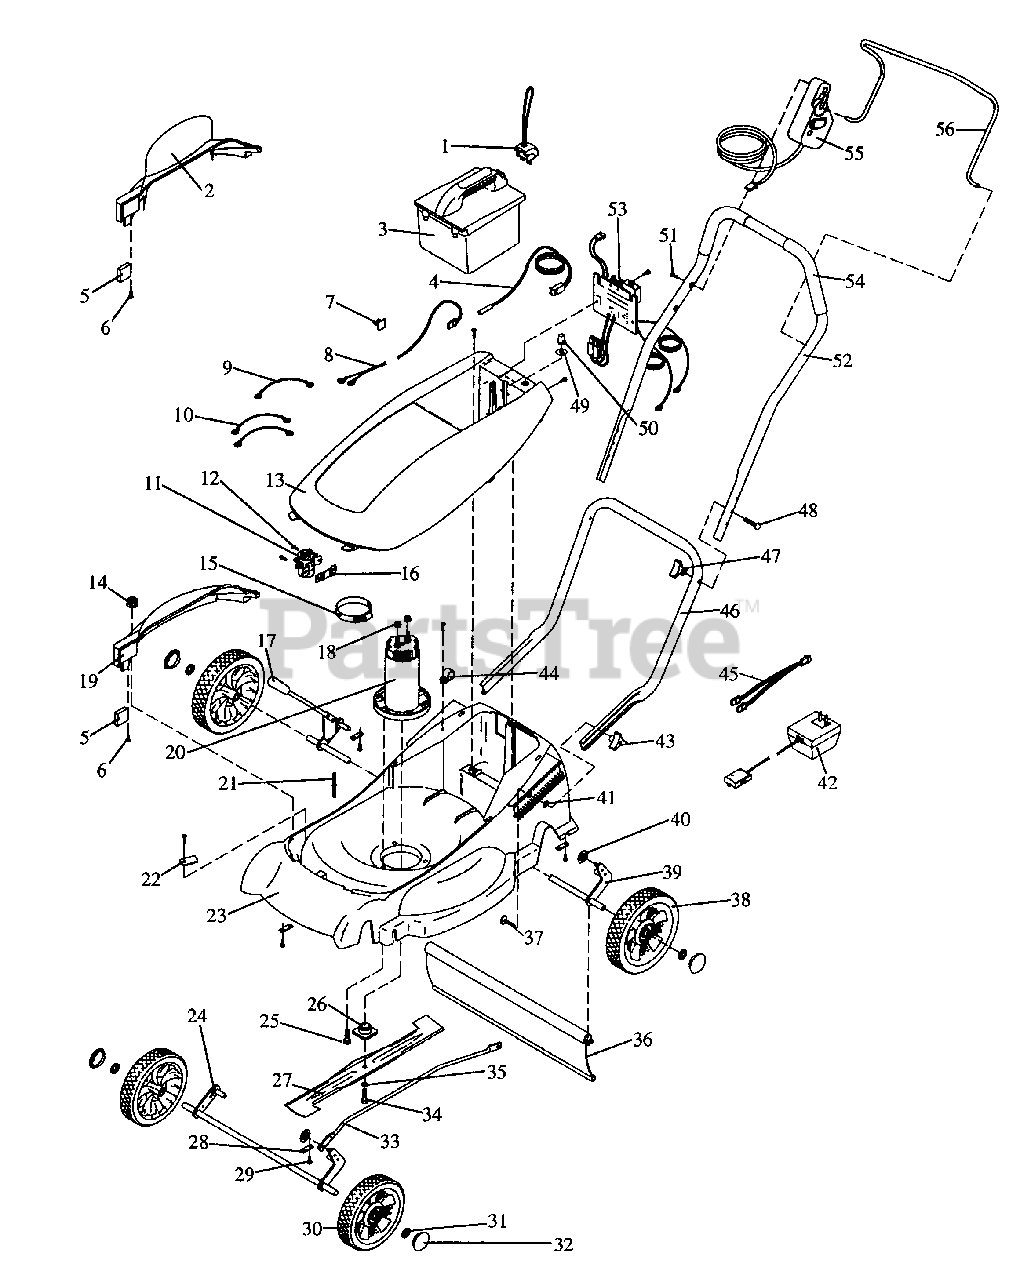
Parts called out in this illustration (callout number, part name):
2	Discharge Chute
3	Battery Pack Assembly
4	Interlock Switch Assembly
7	Cord Clip
8	Circuit Board Wire Assembly
9	Solenoid Wire Assembly
10	Solenoid Wire Assembly
11	Solenoid
12	Solenoid Screw
13	Mower Cover
15	Solenoid Clamp
16	Solenoid Bracket
17	Height Adjustor Handle
18	Motor Nut
19	Mulching Cover
20	Motor
21	Chute Stud
22	Interlock Retainer
23	Mower Deck
24	Height Adjustor, Front
25	Bolt, Motor
26	Blade Adaptor
28	Axle Retainer
30	Front Wheel
31	Wheel Retainer
33	Height Adjustor Link
34	Blade Mounting Bolt
35	Washer, Split Ring
36	Drag Shield
37	Lower Handlebar Bolt
38	Rear Wheel
39	Height Adjustor, Rear
40	Link Retainer
41	Bolt Retainer
42	Charger
43	Handlebar Knob
44	Wire Clamp
45	Harness, Battery Charger
46	Lower Handlebar
47	Handlebar Knob
48	Handlebar Bolt
49	Circuit Breaker Label
50	Circuit Breaker Boot
51	Handlebar Screw
52	Upper Handlebar
53	Motor Control
54	Foam Grip
55	Control Assembly
56	Wire, Bail Assembly
